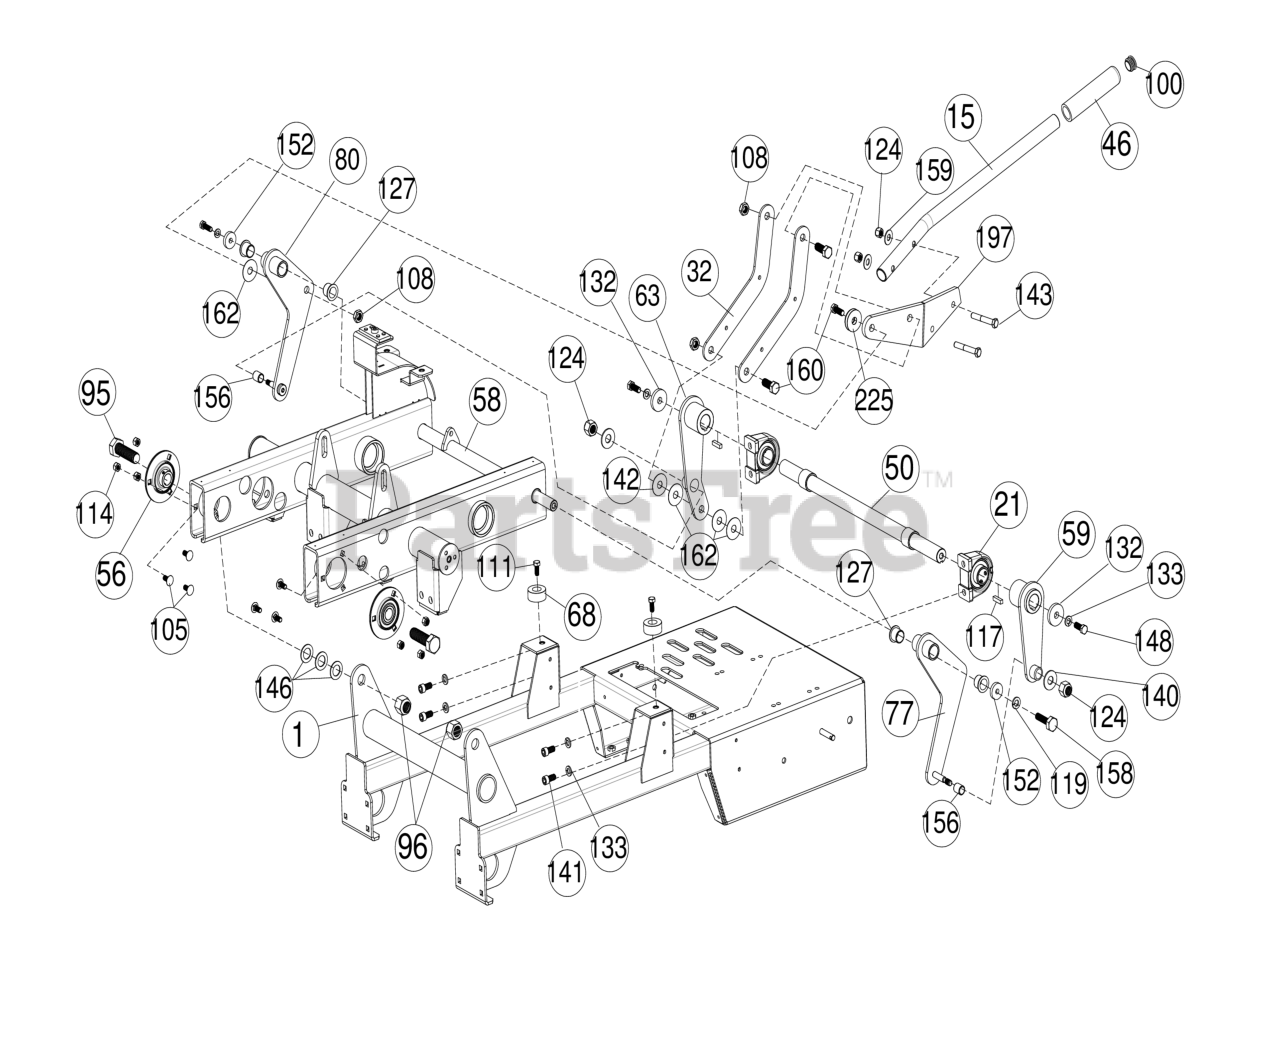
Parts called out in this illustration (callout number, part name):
1	ENGINE BASE WA W/LABELS AE1300H
15	HANDLE TINE WA
21	BEARING LIFT
32	BRACKET HANDLE SUPPORT
46	GRIP HANDLE
50	TINE FRAME LIFT SHAFT WA
56	BEARING AND FLANGETTE ASSY .75"
58	FRAME TINING AE900
59	LIFT ARM LFT WA AE900
63	ARM LIFT RT WA AE900
68	BUMPER RECESS
77	ARM TINE LIFT CONNECTING WA LH
80	ARM TINE LIFT CONNECTING WA RH
95	SCREWCAP 3/4-10 X 2 1/2" LG Z/P GR 5
96	NUT LOCK 3/4" - 10 ZP
100	PLUG TUBE INSERT 1" OD
105	BOLT CARRIAGE 5/16"-18 X 3/4" ZP
108	NUT 1/2"-20 JAM W/LOCK
111	SCREWCAP 5/16"-18X3/4" HCS ZP
114	NUT LOCK 5/16"-18 HEX Z/P
117	KEY SQUARE 1/4" X 1"
119	WASHER LOCK 5/16 ST MED
124	NUT LOCK 3/8"-16 HEX
127	BUSHING PIVOT FRAME AE
128	WASHER 5/16" FLATWASHER Z/P
132	WASHER 1.5 OD X .453 ID X .25 THK
133	WASHER LOCK 3/8" S/T MED
140	WASHER 3/8"SAE 13/32"X13/16"X1/16"
141	SHCS 5/16" -18 X 1.25 BLK OX
142	WASHER 1/2"FC9/16"X1 3/8"X7/64"
143	SCREWCAP 3/8"-16 X 2 1/4" HCS ZP GR 5
146	WASHER .765" ID X 1.25 OD X .06"
148	SCREWCAP 3/8"-24 X 1" HCS GR 8
152	WASHER 1.125 OD X 0.344 ID X .25 THK ZP
156	BUSHING TINE FRAME PIVOT
158	SCREWCAP 5/16"-18 X 1" HCS ZP
159	WASHER 3/8"FC7/16"X1"X5/64"
160	SCREWCAP 1/2-20 X 1 1/4 GR. 5 W/PATCH
162	WASHER NYLON
197	TINE ENGAGE HANDLE MOUNT WA
225	WASHER 33/64 I.D. X 1.50" OD X .25 THK
